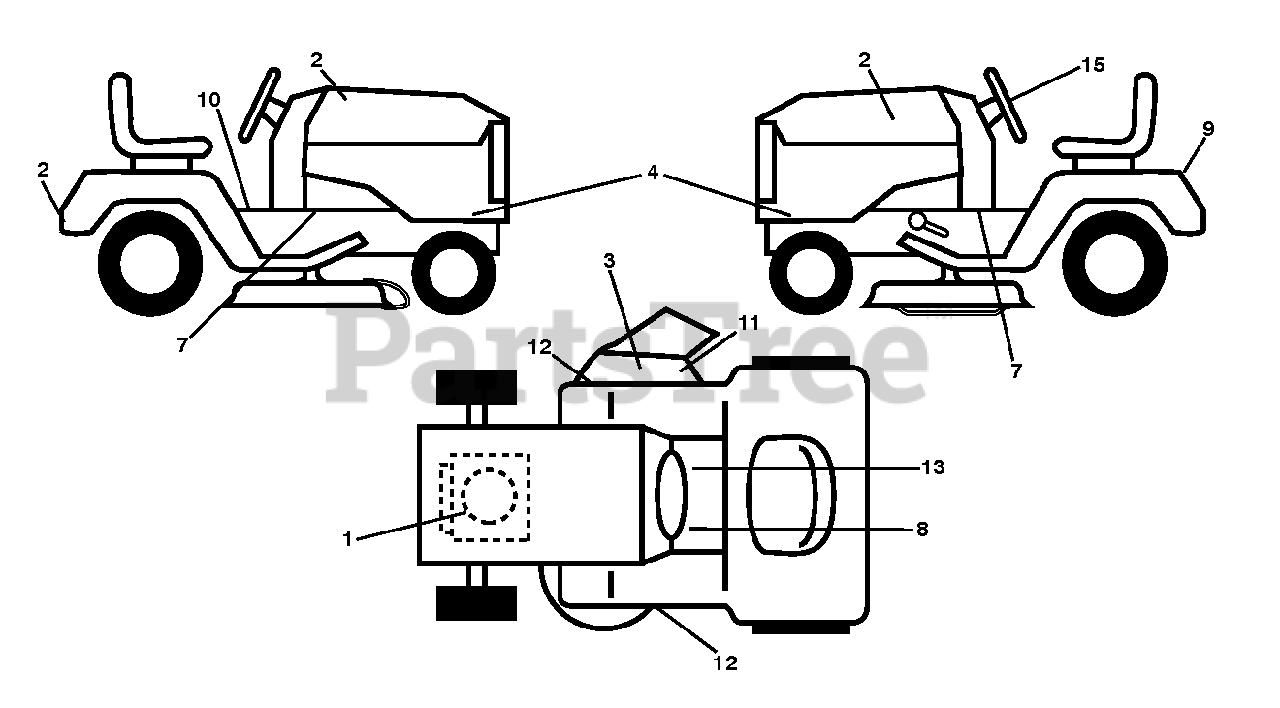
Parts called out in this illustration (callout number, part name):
1	DECAL.ENGINE.WARNING
2	DECAL, DIXON LOGO, DOMED
4	DECAL.DIXON.15/30.AUSTRALIA
7	DECAL.CHASSIS.HOT.MUFFLER
8	DECAL.FNDR.SDLE.BRAKE.CLUTCH.6
9	DECAL BTRY SYMBOLS
10	DECAL.READ.OWN.MAN.SYMBOL.LT
11	DECAL.WARN.DFLCTR/CTFNGR.SRD.
12	DECAL.V.BELT.30"
13	DECAL.PARKING.BRAKE.SADDLE.LT
15	DECAL.WHEEL.STEER.DIXON
